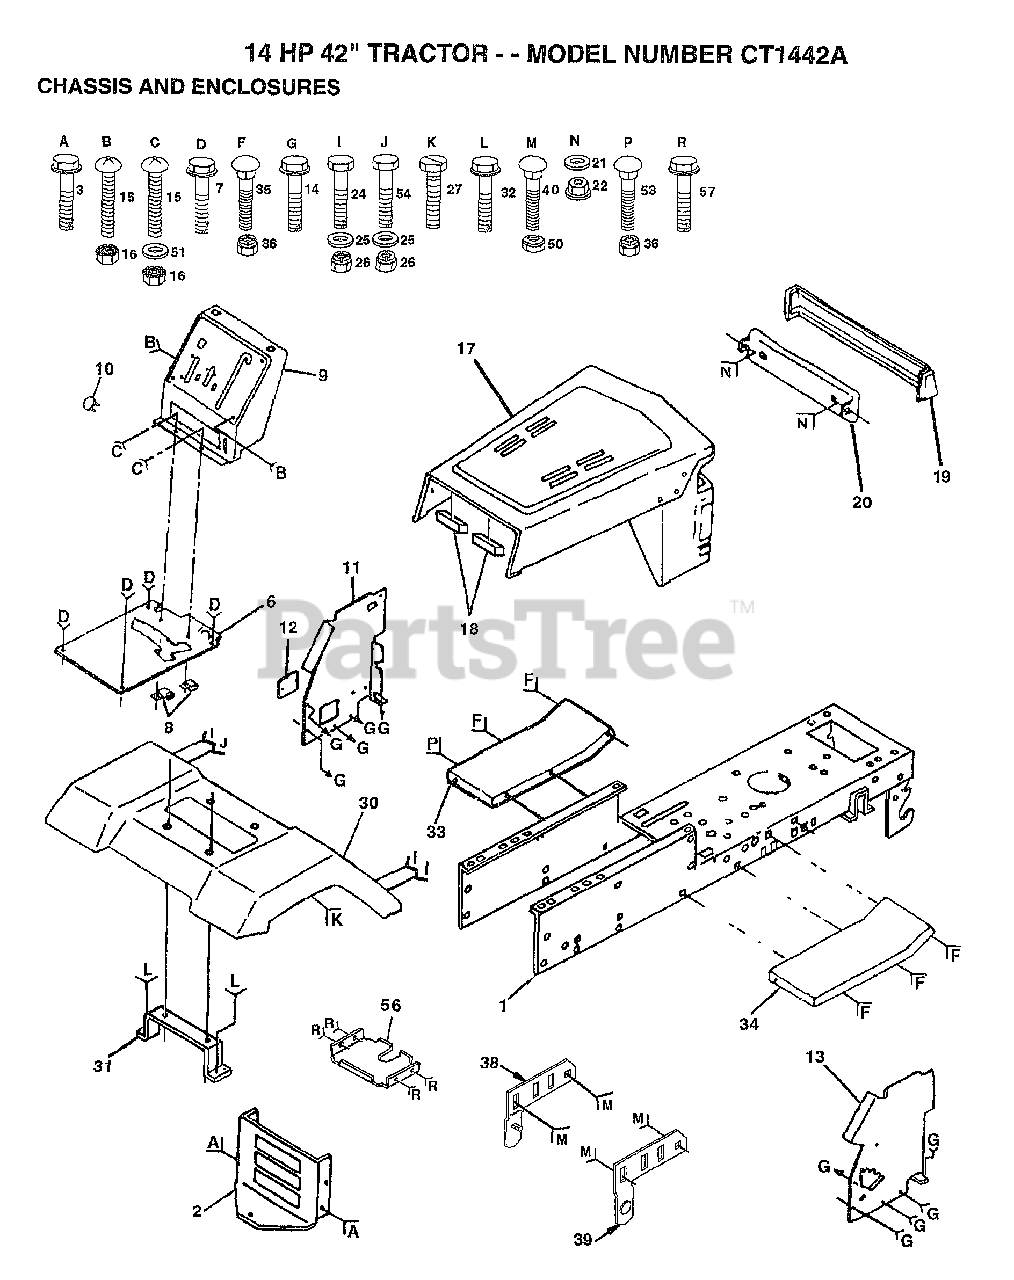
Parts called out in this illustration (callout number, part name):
3	SCREW
7	SCREW LT
8	CLIP T
10	PLUG BUTTON T
11	PANEL DASH LH
12	COVER ACCESS
14	SCREW LT
15	SCREW
17	HOOD/GRILL ASM
21	WASHER PM
22	PAL NUT LT
25	WASHER
27	SCREW LT
31	BRKT FENDER
32	SCREW
33	FOOTREST LH
34	FOOTREST
35	BOLT
38	PIVOT BRKT LH
39	PIVOT BRKT RH
50	NUT
51	WASHER
56	BRKT SUPPORT LT
57	SCREW
